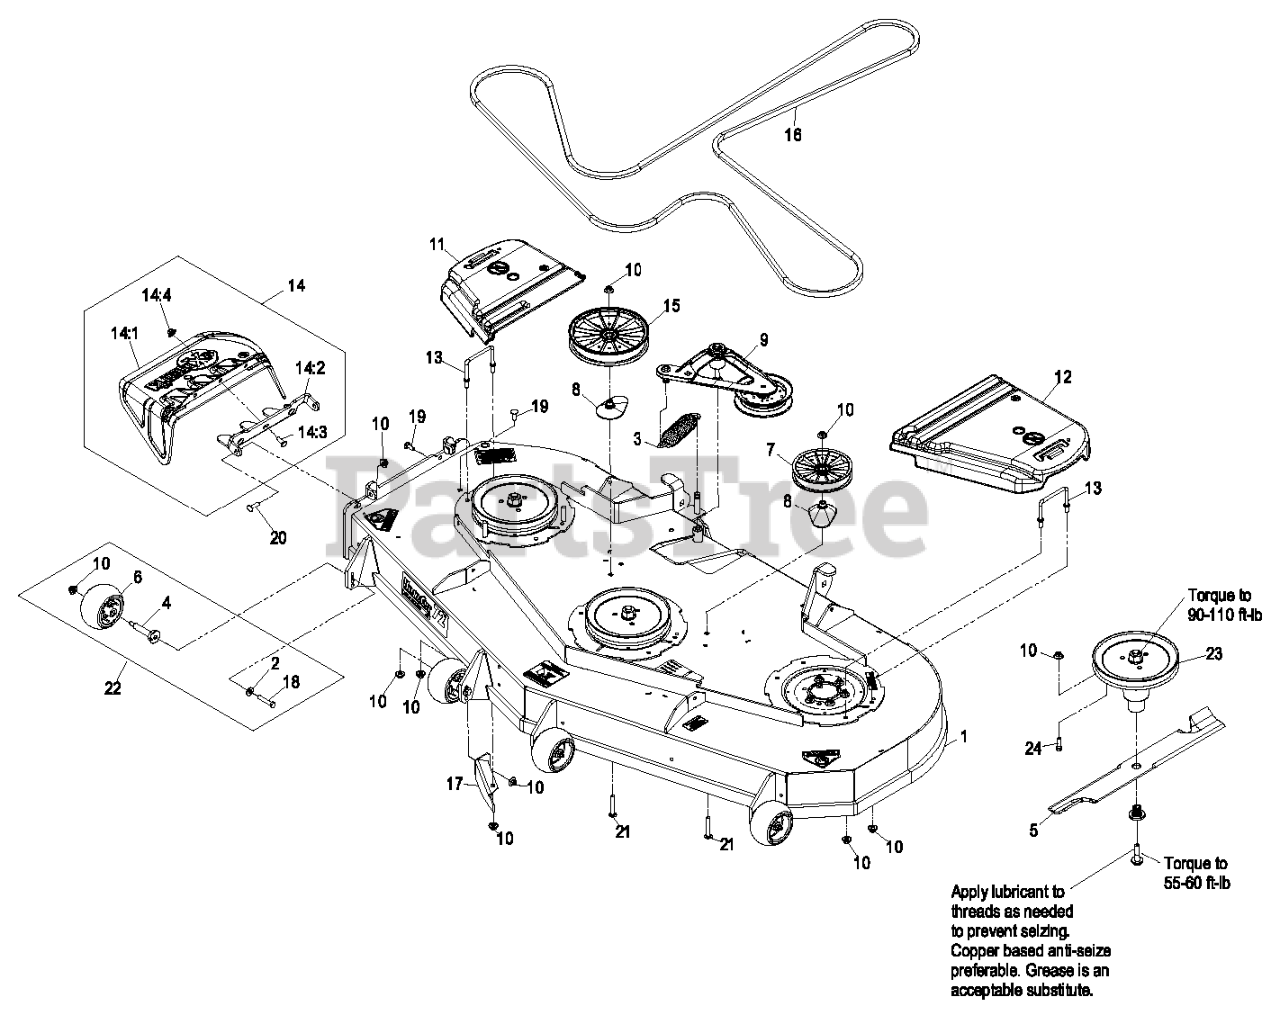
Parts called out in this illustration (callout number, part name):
1	DECK W/DECALS ASM-724
2	WASHER-BELLEVILLE
6	ROLLER-SCALP, ANTI
7	PULLEY,IDLER 6"
8	SPACER-PULLEY
10	Nut-Nyloc 3/8-16 Flg
11	COVER-BELT, RH
12	COVER-BELT, LH
13	WIREFORM-COVER
14	ASM,DISCHARGE CHUTE
14:1	CHUTE,DISCHARGE
14:2	BRACKET,DISCHARGE CHUTE
14:3	SCREW-CARR
14:4	Nut-Nyloc 3/8-16 Flg
15	PULLEY,IDLER 8"FLAT
16	BELT-V
17	BAFFLE,DISCHARGE 726
18	SCREW-HH
19	SCREW-CARR
20	Bolt-Carriage 3/8-16 X 1 1/4
21	SCREW-CARR
23	KIT,CUTTER HOUSING 72
24	Asm, Deck Complete
